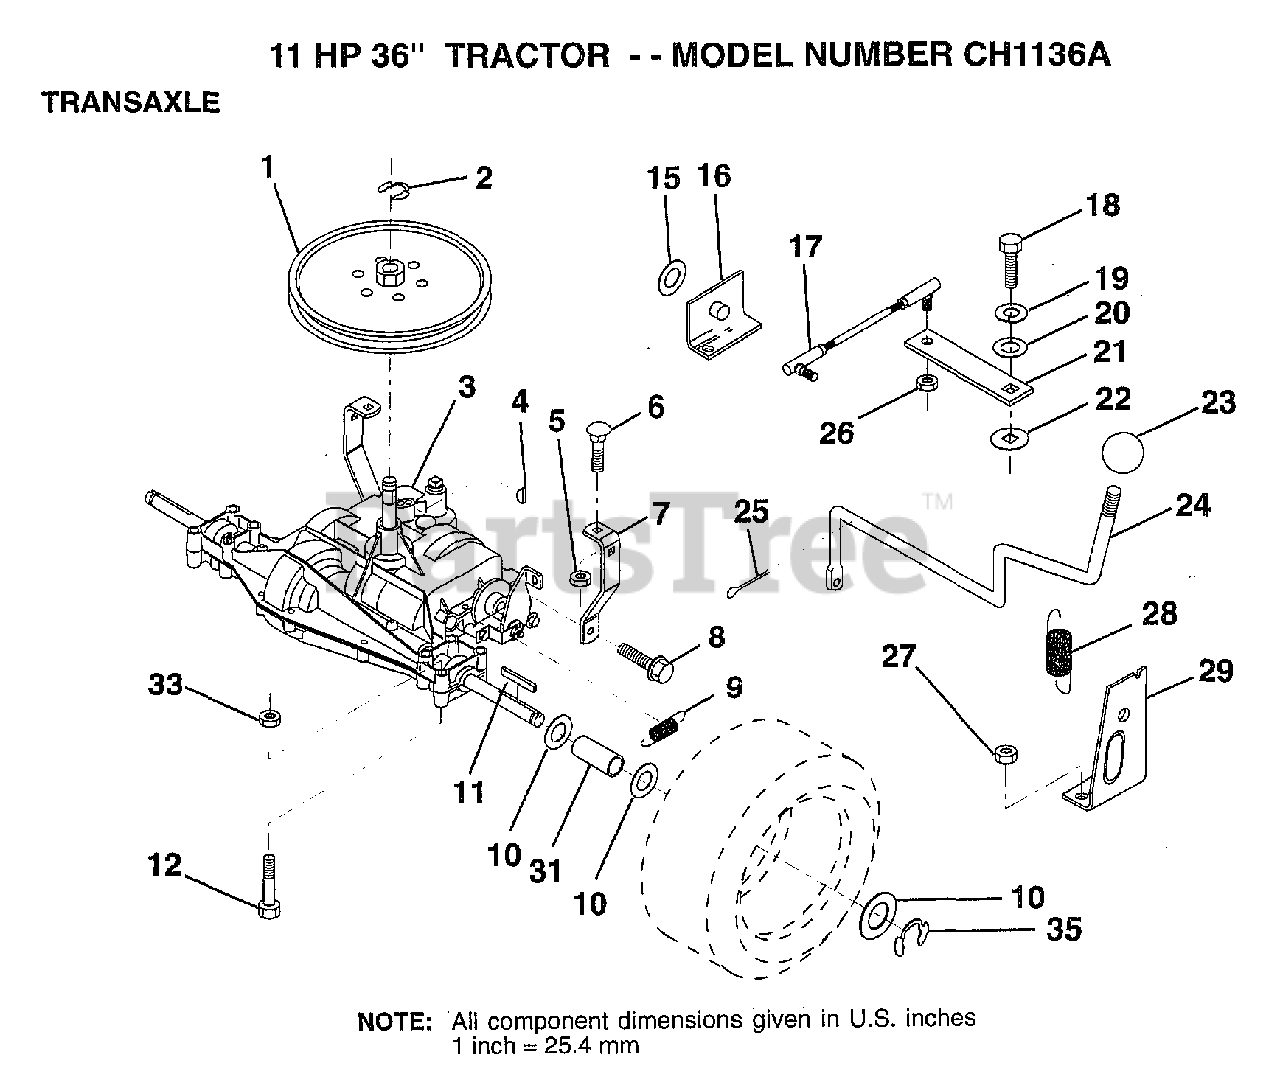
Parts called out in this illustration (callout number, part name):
1	PULLEY
5	NUT
6	BOLT
7	"STRAP,TORQUE"
8	SCREW
10	WASHER
11	SQUARE KEY
12	BOLT
16	"SUPT,HDLE SHT LH"
17	"LINK,SHIFT"
19	LOCKWASHER
20	WASHER LT
21	ARM SHIFT
22	WASH-SHFT PLT LT
23	KNOB T (1/2-HOLE)
24	"ROD,SHIFT"
25	PIN COTTER 1/8
26	NUT.LOCK.5/16-24
28	"SPRING,EXT"
29	"SUPT,HDLE RH"
31	SPACER LT
33	NUT
35	E-RING LT
